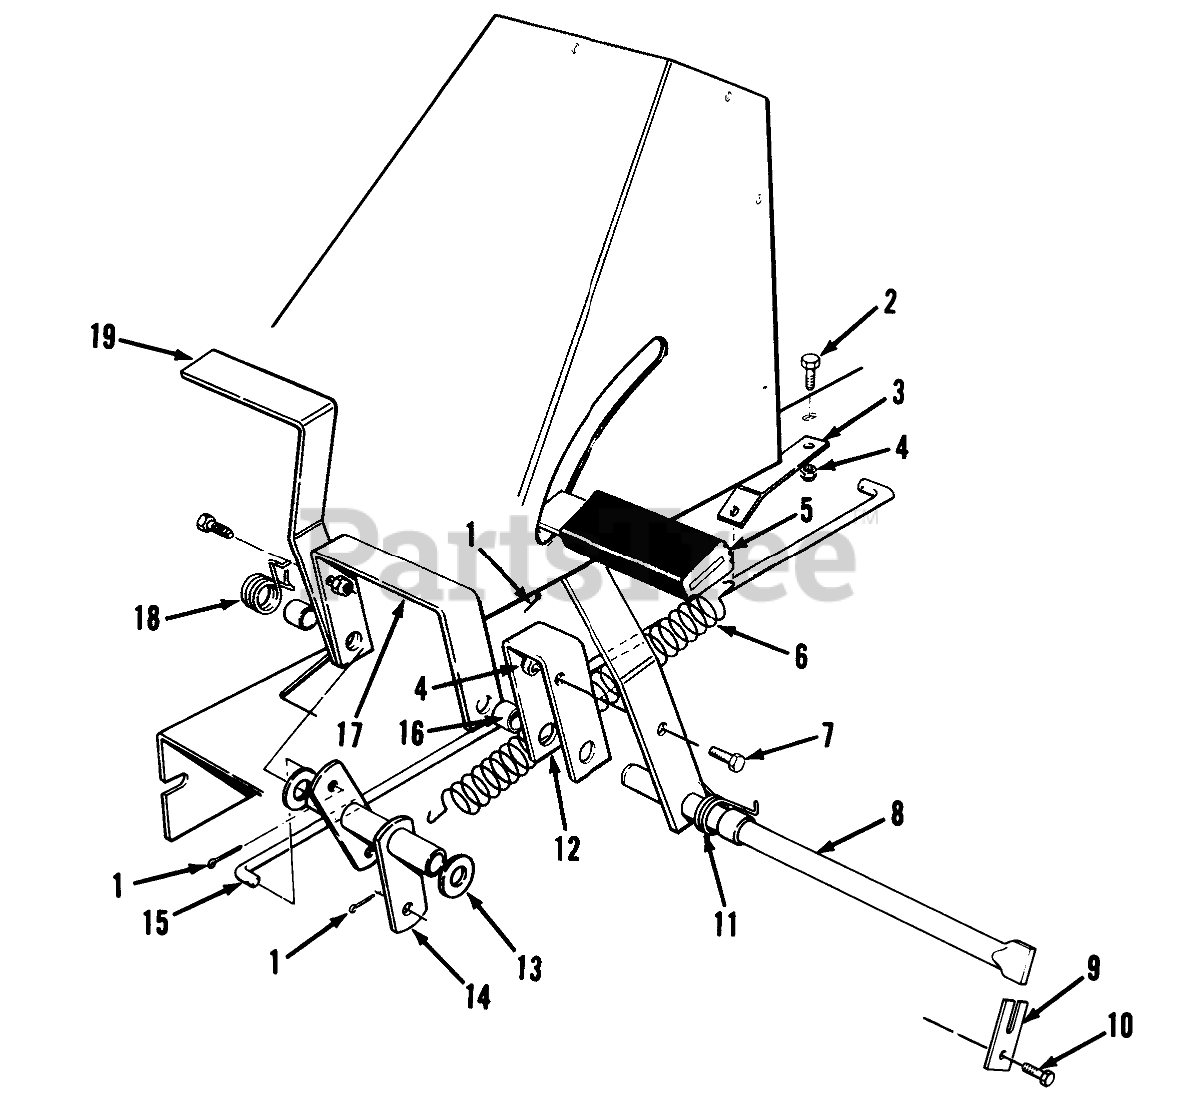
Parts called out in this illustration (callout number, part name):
1	PIN-COTTER
2	SCREW-HH
3	BRKT-SPRING RET
4	NUT-LOCK, NI
5	PAD-PEDAL
6	SPRING-EXTENSION
7	SCREW-HH
8	SHAFT-PEDAL PIVOT
9	RETAINER-SHAFT
10	SCREW-HH
11	SPRING-TORS CLUTCH
12	Bracket-Clutch Pedal
13	WASHER-FLAT
14	Pivot Tube
15	ROD-ENGAGE
16	SPACER-PEDAL
17	Bracket-Brake Pedal
18	SPRING-TORS BRAKE
19	Pedal
